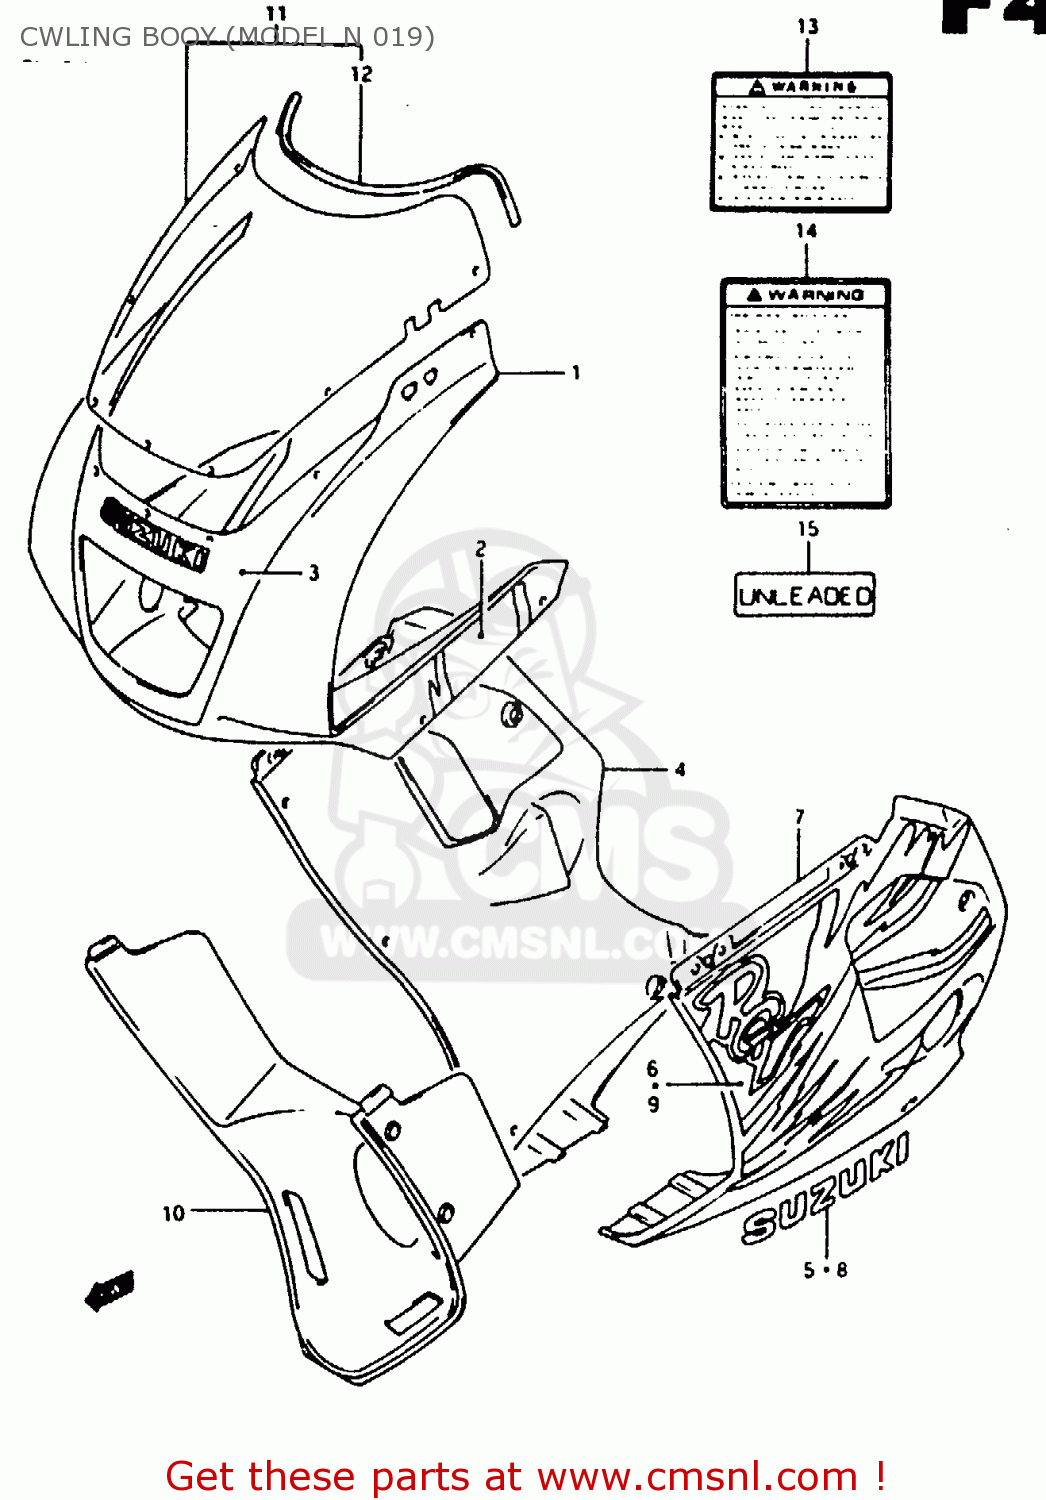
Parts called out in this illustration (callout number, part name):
1	COWLING ASSY, BODY (BLACK)
2	TAPE SET, SIDE
3	TAPE, ZEKKEN
4	COWLING ASSY, UNDER RH (BLACK)
5	EMBLEM
6	TAPE SET, UNDER RH
7	COWLING ASSY, UNDER LH (BLACK)
8	EMBLEM
9	TAPE SET, UNDER LH
10	COWLING, UNDER CENTER (BLACK)
11	SCREEN SET, WIND
12	MOLDING
13	LABEL, WARNING SAFETY
14	LABEL (WARNING SCREEN)
15	LABEL,CAUTION
16	LABEL, TIRE AIR PRESSURE
